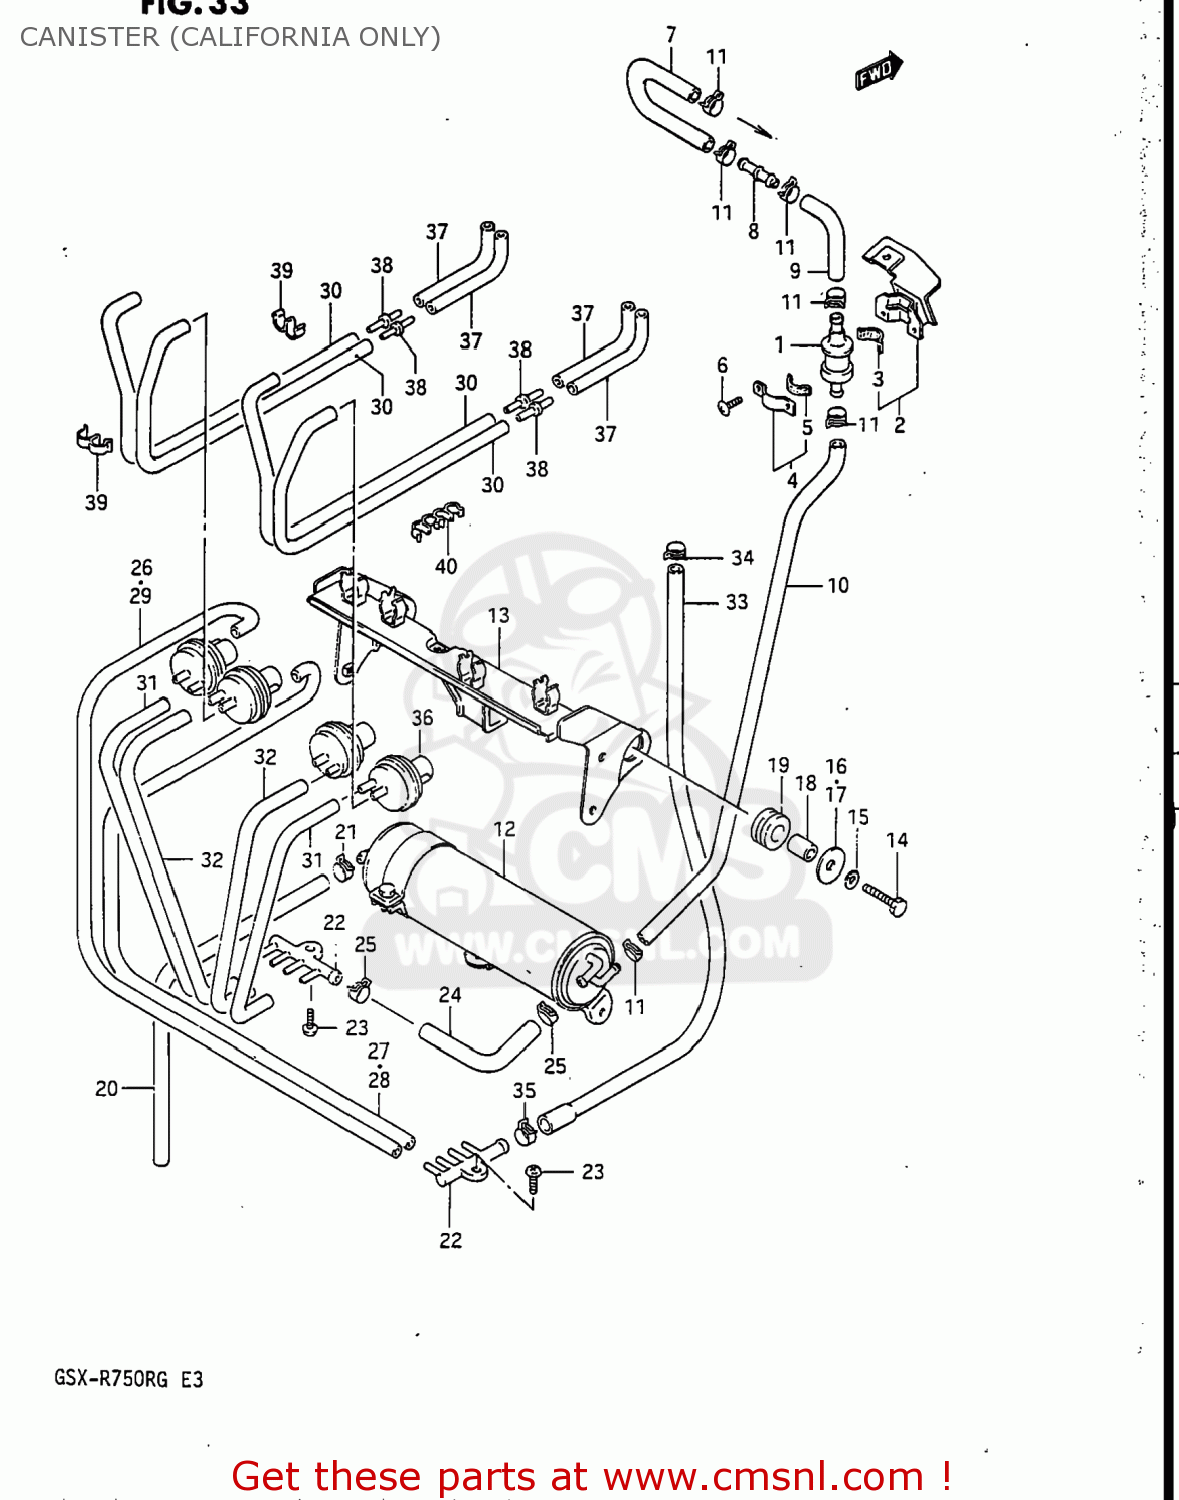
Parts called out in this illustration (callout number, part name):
1	VALVE,FUEL TANK BREATHER
2	(CA) PLATE,FRONT,TANK BRACKET
3	CUSHION
4	PLATE,FUEL TANK BREATHER NO.2
5	CUSHION
6	SCREW
7	HOSE
8	UNION
9	HOSE
10	HOSE
11	(CA) CLIP
12	(CA) CANISTER ASSEMBLY,CHARCOAL
13	(CA) BRACKET COMP,CANISTER
14	BOLT
15	WASHER
16	WASHER
17	WASHER (6.5X22X1.6)
18	SPACER(6.5X11.5X12)
19	CUSHION
20	HOSE
21	CLAMP
22	SEPARATOR
23	SCREW
24	HOSE
25	CLAMP
26	HOSE
27	HOSE
28	HOSE
29	HOSE (22/3.5X7.5X470)
30	HOSE
31	HOSE
32	HOSE
33	HOSE
34	(CA) CLIP
35	CLAMP
36	(CA) VALVE,VACUUM CONT
37	HOSE
38	2 WAY
39	CLAMP
40	CLIP
